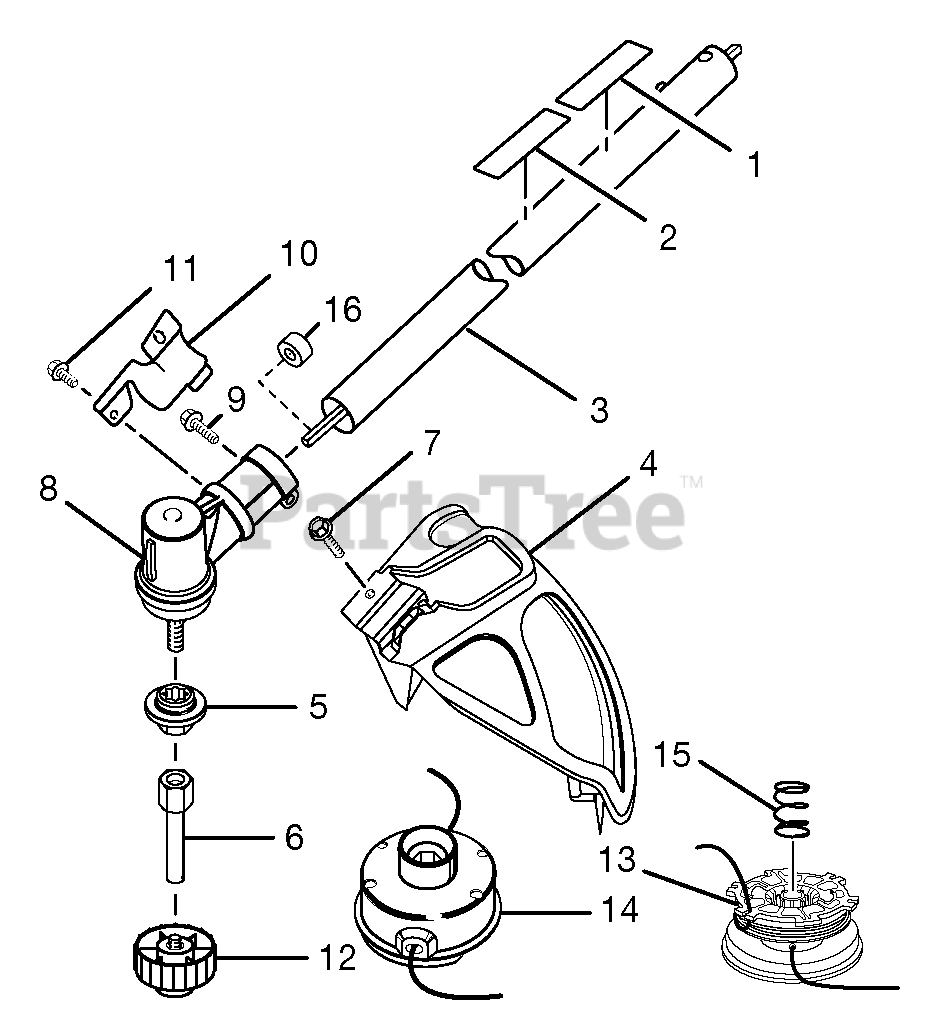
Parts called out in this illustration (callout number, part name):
1	Expand-it Label
2	Warning Decal
3	Straight Shaft Assembly
4	Grass Deflector Assembly
5	Flanged Washer
6	Shaft Adapter
7	Screw (1/4-20 x 0.70-0.75 in.)
8	Gear Case Assembly
9	Screw (1/4-20 x 1-1/4 in.)
10	Clamp
11	Screw (10-24 x 5/8 in. Hex Hd.)
12	Spool Retainer (Red)
13	Spool and String (.095 in.)
14	Complete String Head Assembly (.095 in.)
15	Compression Spring
